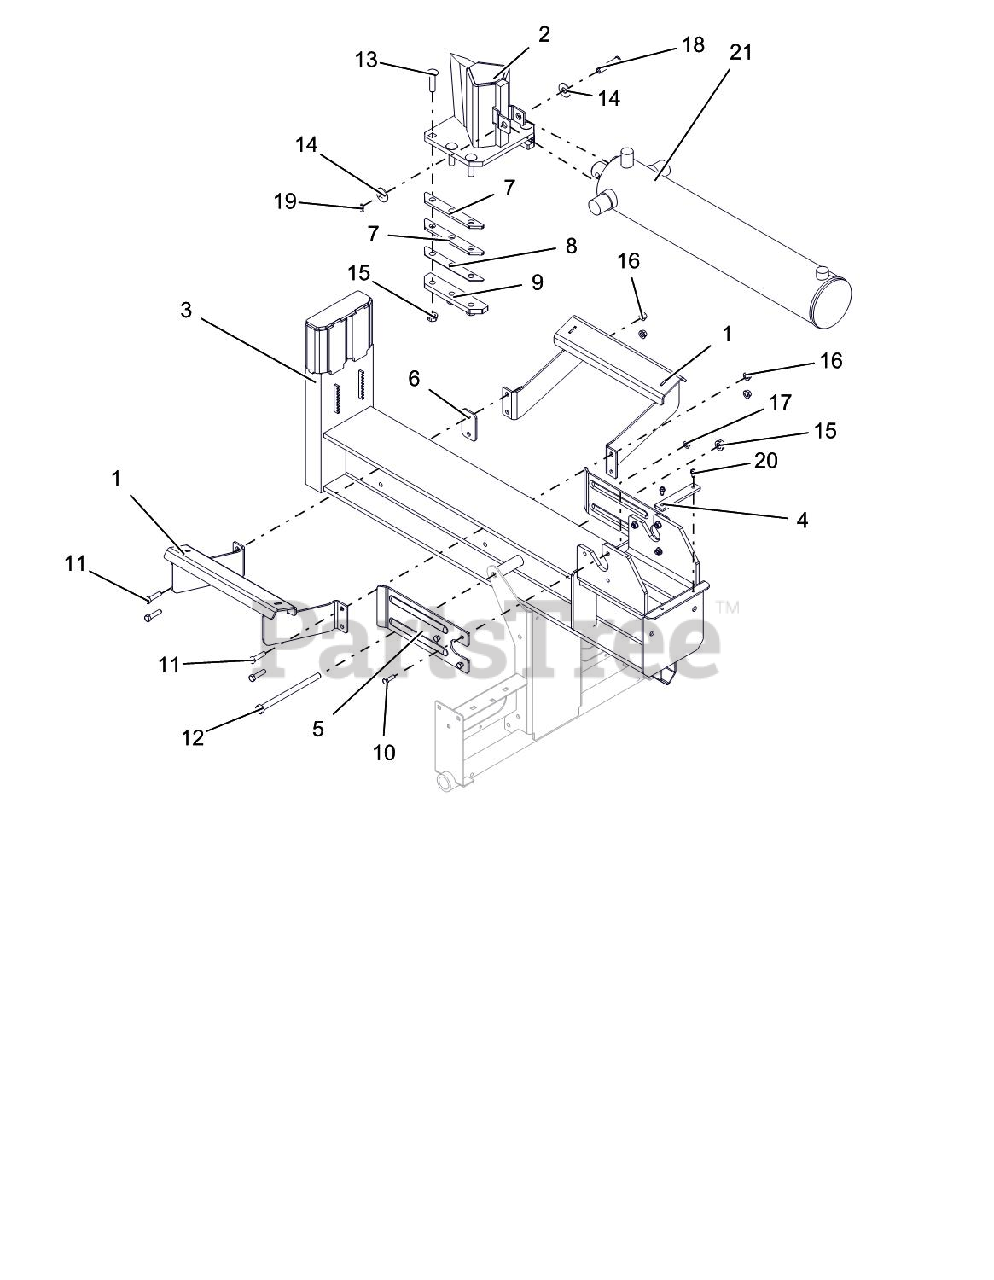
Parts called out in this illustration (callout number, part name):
1	WLDMT, LOG CRADLE
2	WLDMT, SPLITTER WEDGE
3	WLDMT, CE SPLITTER BEAM
4	SPACER, CYLINDER
5	PLATE,STRIPPER
6	PLATE, WORK TABLE SPACER
7	SPACER, WEDGE
8	SHIM,SPLITTER WEDGE
9	RETAINER,WEDGE
10	@BLT-HEX .31-18X1.00 GR5 YWZC
11	@BLT-HEX .38-16X1.50 GR5 YWZC
12	@BLT-HEX .50-13X7.50 GR5 YWZC
13	BLT-RDHDSQNKFTH.50-13X2 G8YWZC
14	@WSHR-FL-STL.563X1.38X.109YWZC
15	NUT-LK-CTR-FLG .50-13 YWZC
16	@NUT-LK-TOP-FLG .38-16 YWZC
17	@NUT-LK-TOP-FLG .31-18 YWZC
18	PIN-CLEV .50X2.50X2.27 YWZC
19	CLIP, SPRING
20	SCR-TAP .25-20X.50 HWH TR YWZ
21	CYLINDER W/SAFETY DECALS-27TCE
